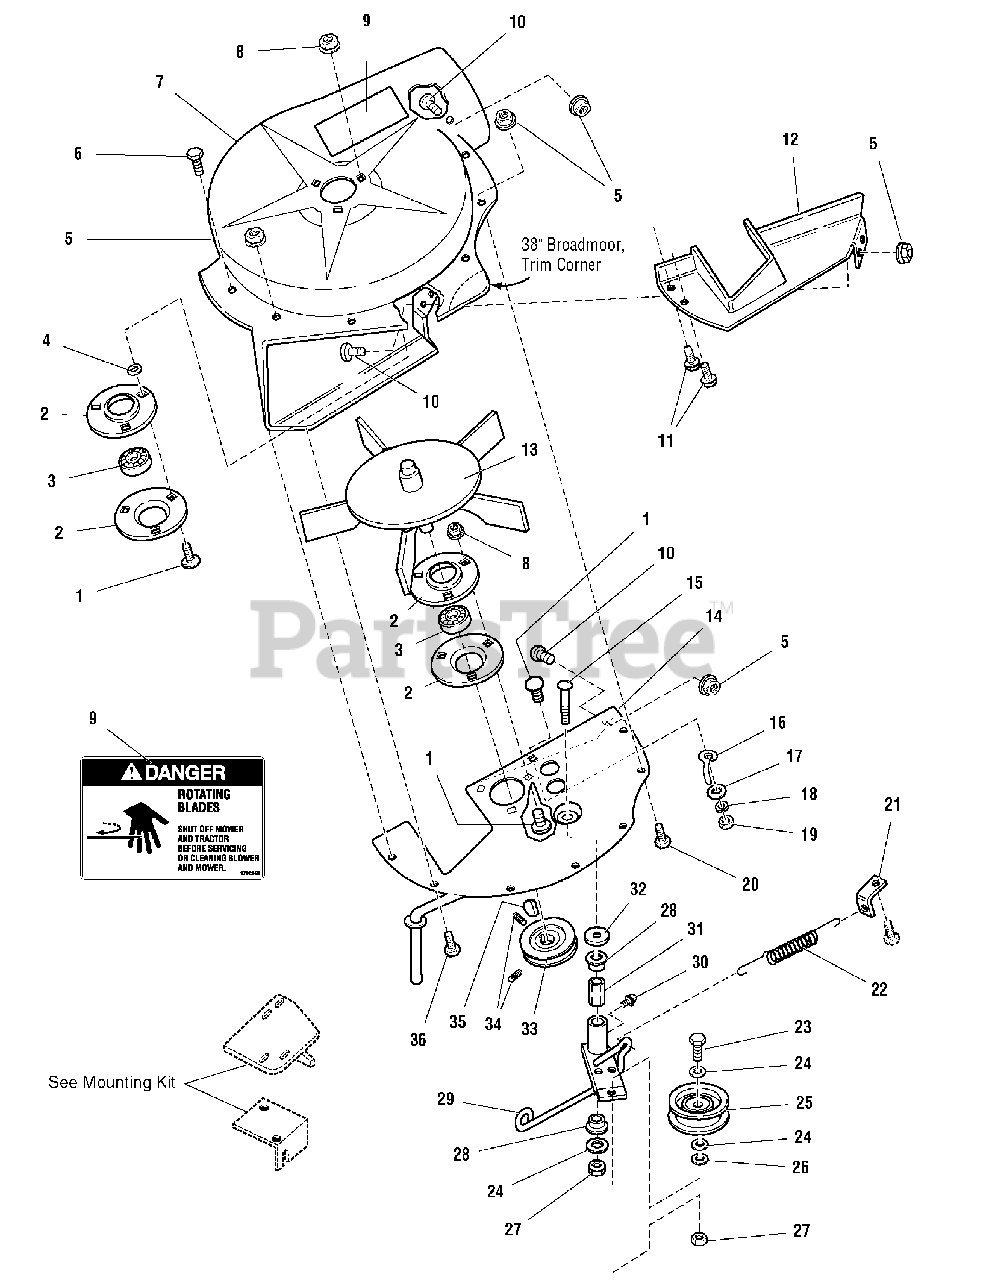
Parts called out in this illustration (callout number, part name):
1	BOLT, Carriage, 5/16-18 x 3/4
2	RETAINER, Bearing
3	BEARING
4	PUSH NUT, 3/8 x 5/8 OD
5	NUT, Hex, Flange Lock, 1/4-20
6	CAPSCREW, Hex, Taptite, 1/4-20 x 1/2
7	FAN HOUSING (Includes Decal)
8	NUT, Flange Whizlock, 5/16-18
9	DECAL, Danger, Blower
10	BOLT, Carriage, 1/4-20 x 3/4
11	CAPSCREW, Washer Head, Plastite, 1/4-18 x 5/8
12	COVER, Bottom
13	FAN ASSEMBLY, 5 Blade
14	PLATE ASSEMBLY
15	BOLT, Carriage, 3/8-16 x 2-1/4
16	BELT STOP
17	WASHER, Flat, 5/16 x 7/8 OD
18	WASHER, Spring Lock, 5/16
19	NUT, Hex, 5/16
20	CAPSCREW, Hex Head, 1/4-20 x 7/8
21	BRACKET, Anchor, Spring
22	SPRING, Tension
23	CAPSCREW, Hex Head, 3/8-16 x 1-1/4
24	WASHER, Flat, 3/8 x 7/8 OD
25	IDLER PULLEY ASSEMBLY
26	WASHER, Flat, 7/16 x 1-1/4 OD
27	NUT, Hex, Jam, Center Lock, 3/8-16
28	SPACER, 3/8 ID x 5/8 OD x 1-3/4 Long
29	LEVER ASSEMBLY, Turbo (Includes Ref. Nos. 30 & 31)
30	FITTING, Grease
31	BUSHING
32	WASHER, Flat, 1/2 x 1-1/4 OD
33	PULLEY, Driven
34	SETSCREW, Hex, Socket Head, 5/16-18 x 5/16
35	KEY, Woodruff, Modified
36	CAPSCREW, Hex Head, 1/4-20 x 5/8
